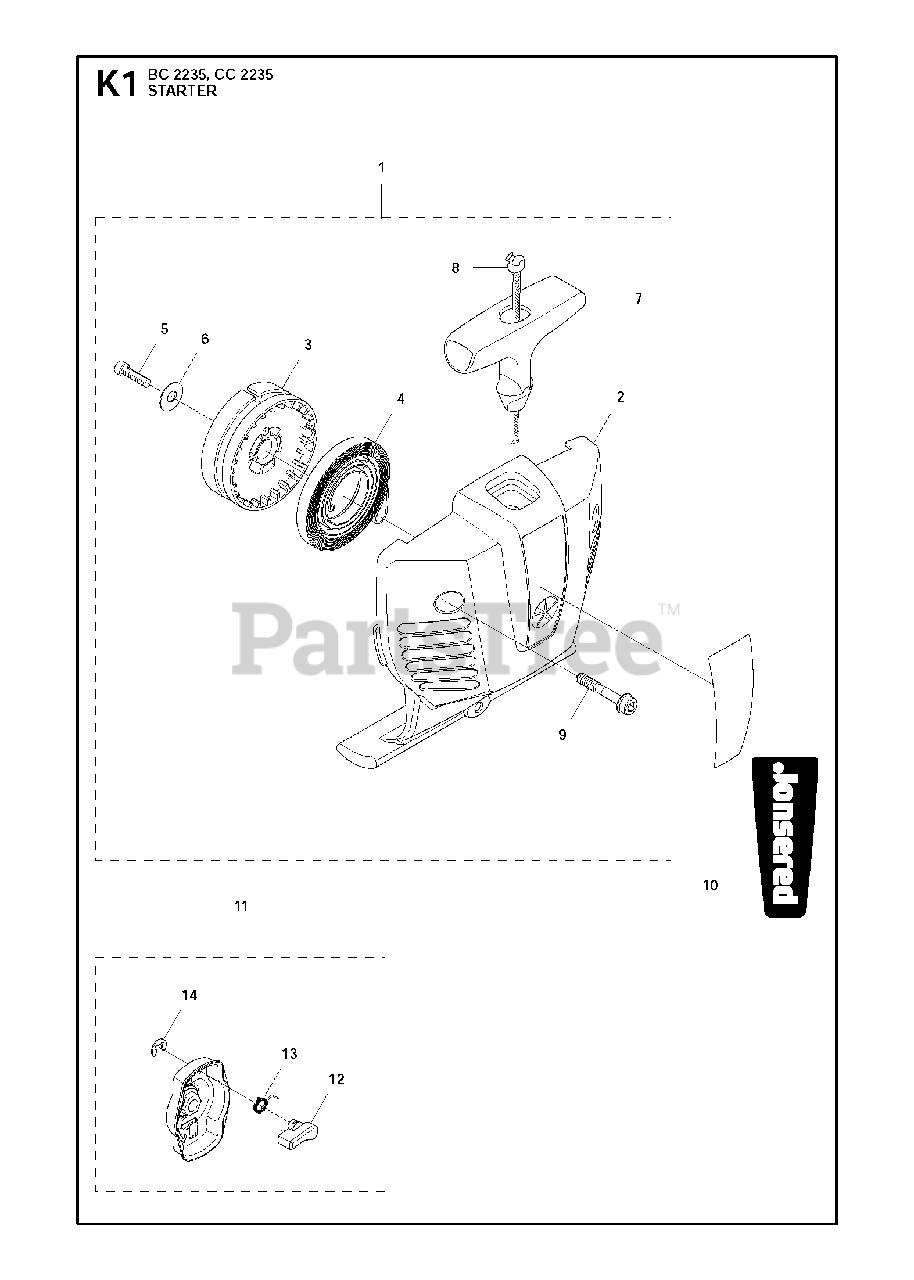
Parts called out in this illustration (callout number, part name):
1	STARTER HOUSING
2	STARTER HOUSING
3	%STARTER PULLEY
4	STARTER SPRING
5	SCREW
6	WASHER
7	HANDLE
8	STARTER ROPE
9	SCREW IHSCFMO
11	STARTER PAWL BRIDGE
12	STARTER PAWL
13	SPRING
14	E-RING 4
